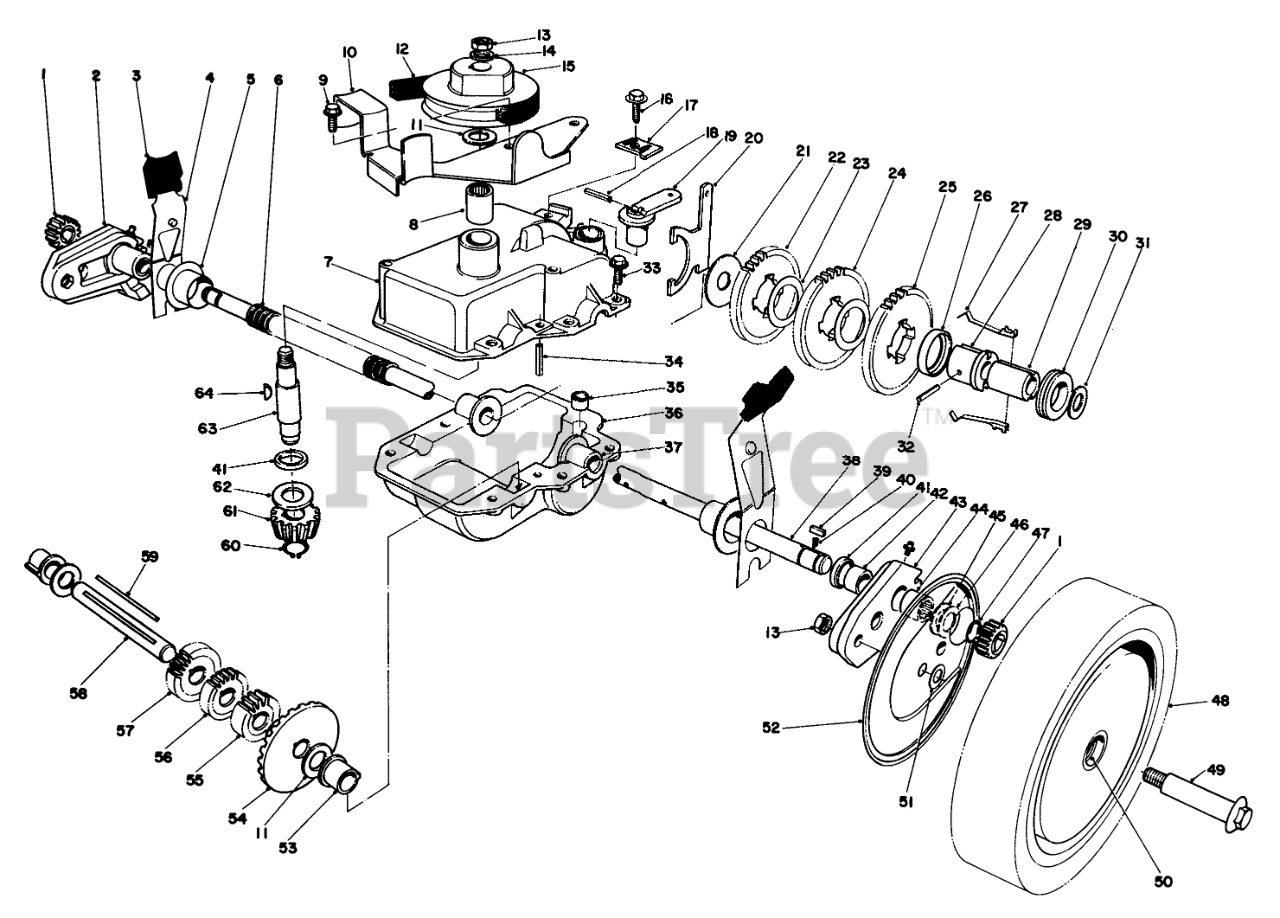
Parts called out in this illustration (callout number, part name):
1	GEAR-PINION
2	Pivot Arm Assembly-R.H. (Incl. Ref. #41, 42 & 44)
3	KNOB-ARM
4	SPRING ARM ASM SP
5	CAP-END
6	CONDUIT-CONVOLUTED, SPLIT
7	Case-Upper
8	Bearing
9	SCREW
10	Bracket-Belt Guide
11	Washer
12	V-BELT
13	Nut
14	WASHER-FLAT
15	PULLEY
16	SCREW-HWHTF
17	Cable Clamp
18	PIN-COIL
19	LEVER-SHIFT
20	Shift Yoke
21	WASHER
22	GEAR-38T
23	WASHER
24	GEAR-42T
26	KEY RETAINER
27	Key
28	Body-Sleeve
29	SLEEVE
30	COLLAR-SHIFT
31	WASHER-PLAIN
32	PIN-SPRING
33	Screw-Tapping
34	ROLL PIN 3/16 X 1 IN
35	BUSHING-YOKE
36	LOWER GEAR CASE CAST
37	Bushing-Output Shaft
38	Output Shaft
39	KEY RECTANGULAR
40	SPRING-COMPRESSION
41	Seal
42	Bushing
43	Pivot Arm Assembly-L.H. (Incl. Ref. #41, 42 & 44)
44	Needle Baring
45	Washer
46	THRUST WASHER
47	RING-RETAINING
48	Wheel, Tire & Gear Assembly (Incl. Ref. #50)
49	BOLT-WHEEL
50	BUSHING
51	WASHER
52	WHEEL COVER
53	BUSHING
54	BEVEL GEAR
55	GEAR-12T
56	GEAR-14T
57	GEAR-18T
58	INTERMEDIATE SHAFT
59	Key Square
60	RING-RETAINING
61	PINION-BEVEL
62	Thrust Washer
63	Input Shaft
64	KEY-WOODRUFF
